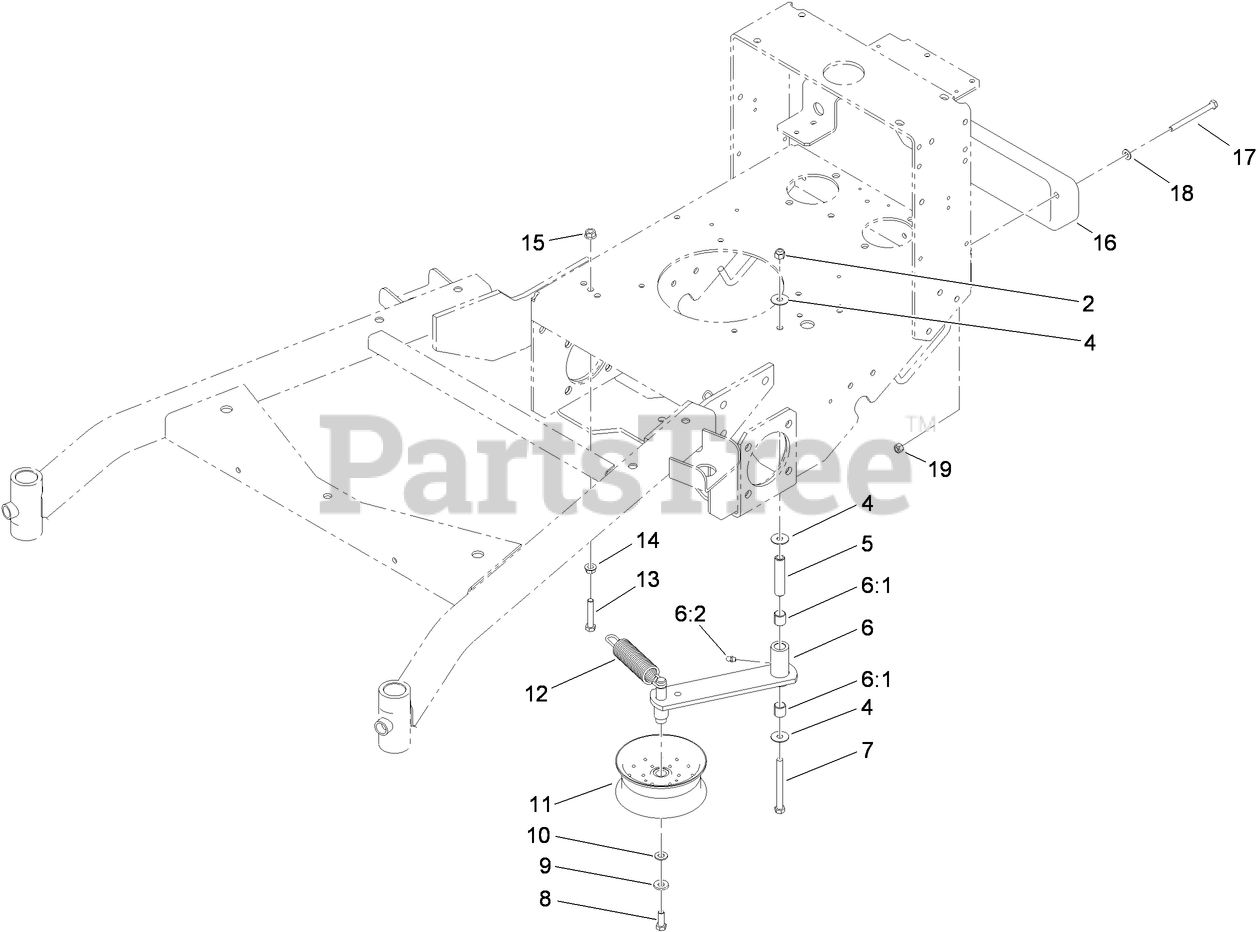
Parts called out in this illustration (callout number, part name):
2	NUT-LOCK, NI
4	WASHER
5	TUBE-IDLER
6	IDLER ARM ASM
6:1	SLEEVE-BEARING
6:2	FITTING-GREASE
7	SCREW-HH
8	SCREW-HH
9	WASHER-BELLEVILLE
10	WASHER-FLAT
11	IDLER-PULLEY, FLAT
12	SPRING-EXTENSION
13	SCREW-HH
14	NUT-HHF, WHIZ
15	NUT-HF
16	WEIGHT-CAST
17	SCREW-HH
18	WASHER-PLAIN
19	NUT-LOCK, NI
